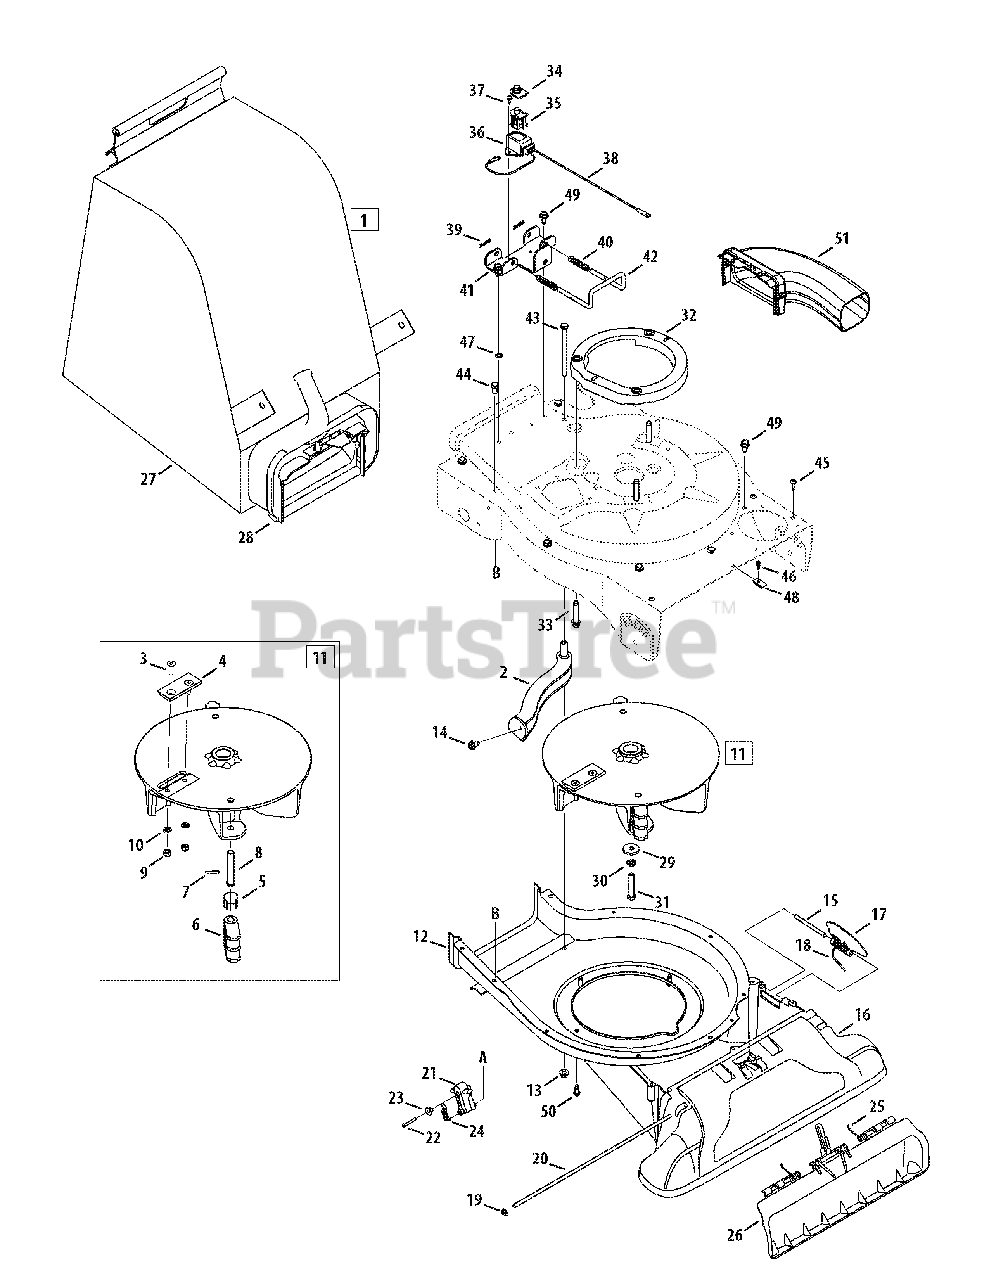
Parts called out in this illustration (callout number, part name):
1	Bag Assembly
2	Screen Assembly
3	Hex Screw 5/16-24 x 1.0
4	Chipper Blade
5	Pin Clip
6	Flail
7	Spiral Pin
8	Clevis Pin
9	Lock Nut, 5/16-24
10	Lock Washer, 5/16
11	Impeller Assembly
12	Lower Flail Housing
13	Flange Lock Nut 5/16-18
14	Screw, 5/16-18 x.500
15	Hinge Pin
16	Nozzle
17	Base Adapter Door
18	Torsion Spring
19	Cap Speed Nut 1/4
20	Pivot Rod
21	Nozzle Door Lever
22	Hex Screw, #8-18 x 1.25
23	Shoulder Spacer
24	Extension Spring
25	Nozzle Door Torsion Spring
26	Nozzle Door
27	Bag
28	Chute Assembly
29	Flat Washer.375 ID x 1.25 OD
30	Lock Washer 3/8
31	Hex Cap Screw, 3/8-24 x 2.75
32	Engine Spacer Assembly
33	Screw, 3/8-16 x 1.875
34	Switch Cover
35	Safety Switch
36	Safety Switch Cover
37	Hex Washer Screw #10-16 x.50
38	Wire Harness
39	Cotter Pin
40	Compression Spring
41	Mounting Bracket
42	Lock Rod
43	Hex Cap Screw 5/16-18 x 4.5
44	Hex Cap Screw 5/16-18 x.625
45	Screw, #12-16 x.750
46	Screw #10 - 16 x.500
47	External L-Washer 5/16
48	Speed Nut
49	Hex Index Screw, 5/16-12 x.750
50	Shoulder Screw, #12-24 x .30 x .46
51	Blower Chute
